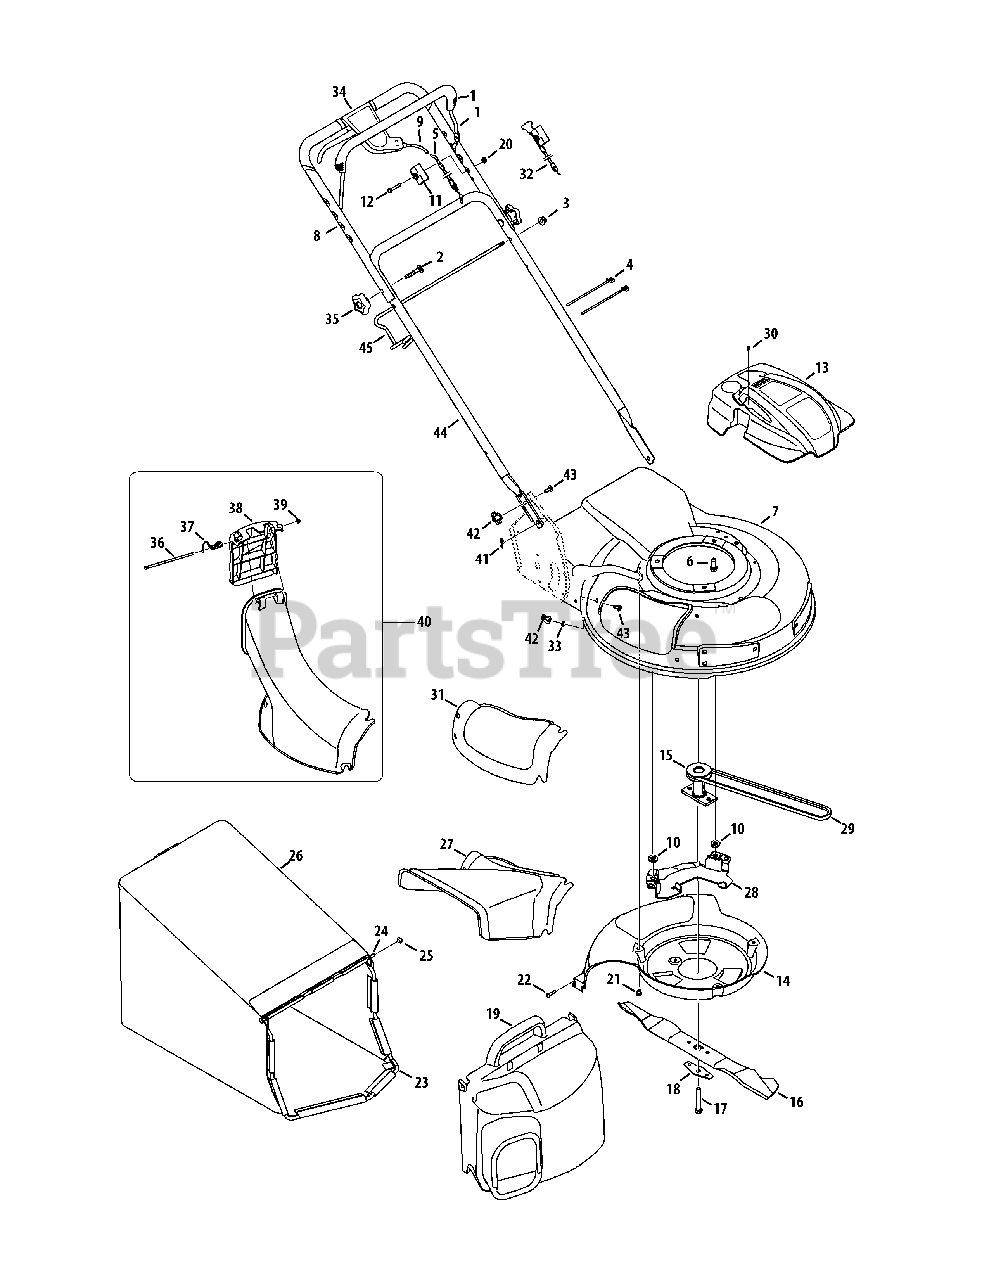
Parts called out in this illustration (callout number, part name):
1	Blade Control Assembly
2	Carriage Bolt 5/16-18 x 2
3	Flange Lock Nut, 5/16-18
4	Cable Tie
5	Control Cable
6	TT Screw, 3/8-16 x 1.00
9	Drive Cable
10	Washer, Flat, .407 x .812 x .135
11	Control Cable Mount
12	Screw, 1/4-20 x 1.50
13	Engine Shroud
14	Rear Baffle
15	Blade Adapter - Kohler
16	21-inch Mulching Blade
17	HH Cap Screw, 3/8-24 x 2.50
18	Bell Blade Spacer
19	Grass Bag Cover Assembly
20	Flange Lock Nut 1/4-20
21	TT Screw 1/4-20 x .375
22	HL Screw 1/4-15 x .75
23	Grass Bag Frame
24	Grass Bag Pivot Rod
25	Cap Speed Nut
26	Grass Bag Assembly
27	Side Discharge Chute
28	Belt Keeper
30	Screw, #12-16 x 1.00
31	Mulch Cover
32	Choke Cable
34	Drive Control Assembly
36	Chute Door Pivot Rod
37	Torsion Spring
38	Top Discharge Door Chute
40	Top Discharge Chute Assembly
41	Cotter Pin
42	Wing Nut
43	Carriage Screw 1/4-20 x .75
45	Grass Bag Support Rod
